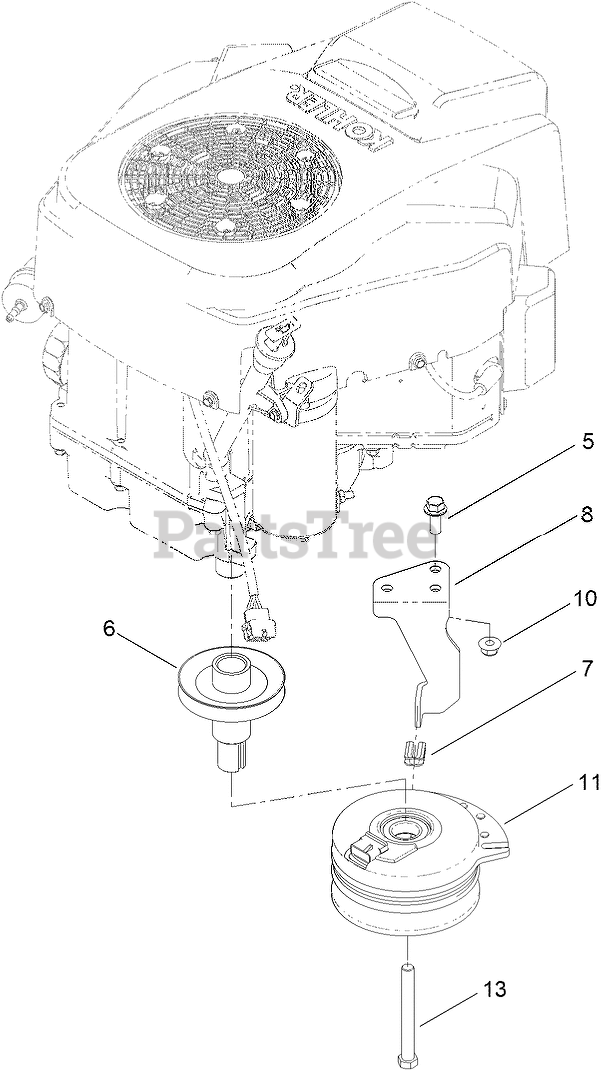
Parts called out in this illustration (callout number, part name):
5	SCREW-HHF
6	PULLEY-ENGINE
7	ISOLATOR-CLUTCH
8	STOP-CLUTCH
10	NUT-HF, NI
11	CLUTCH-ELECTRIC
13	SCREW-HH
